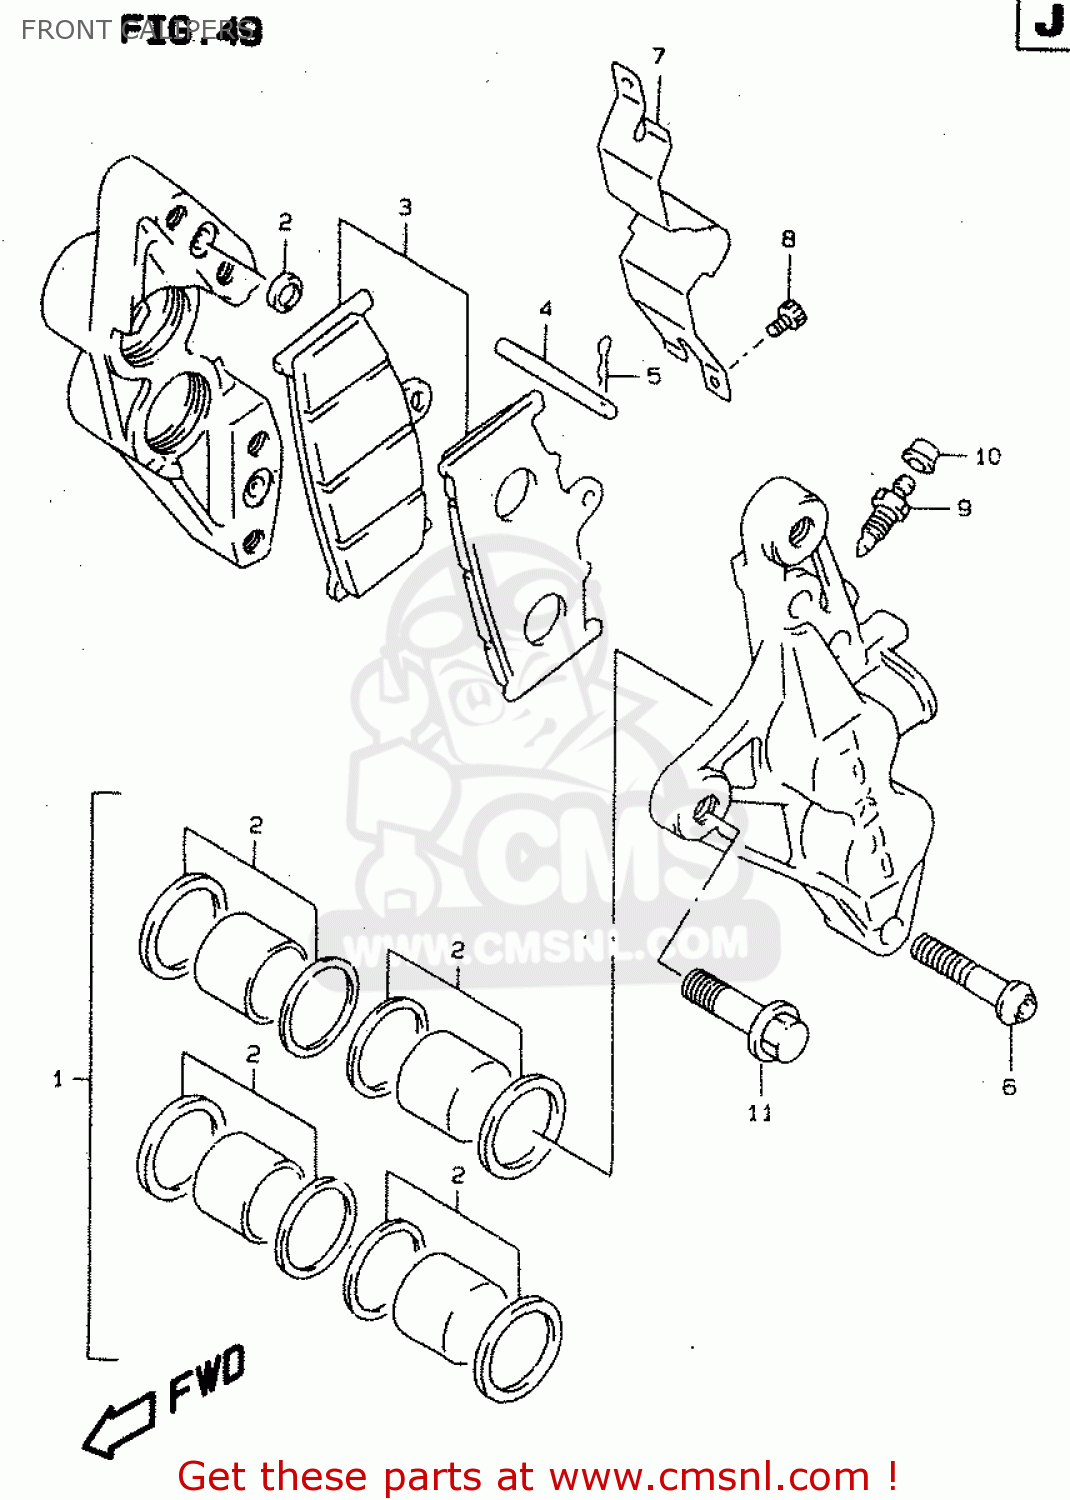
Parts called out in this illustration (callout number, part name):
1	PISTON SET
2	SEAL SET,PISTON
3	PAD SET (NAS)
4	PIN,PAD
5	CLIP,PAD PIN
6	BOLT,HOUSING
7	COVER,CALIPER DUST,R
8	SCREW
9	BLEEDER
10	CAP,BLEEDER PLUG
11	BOLT(10X30)
